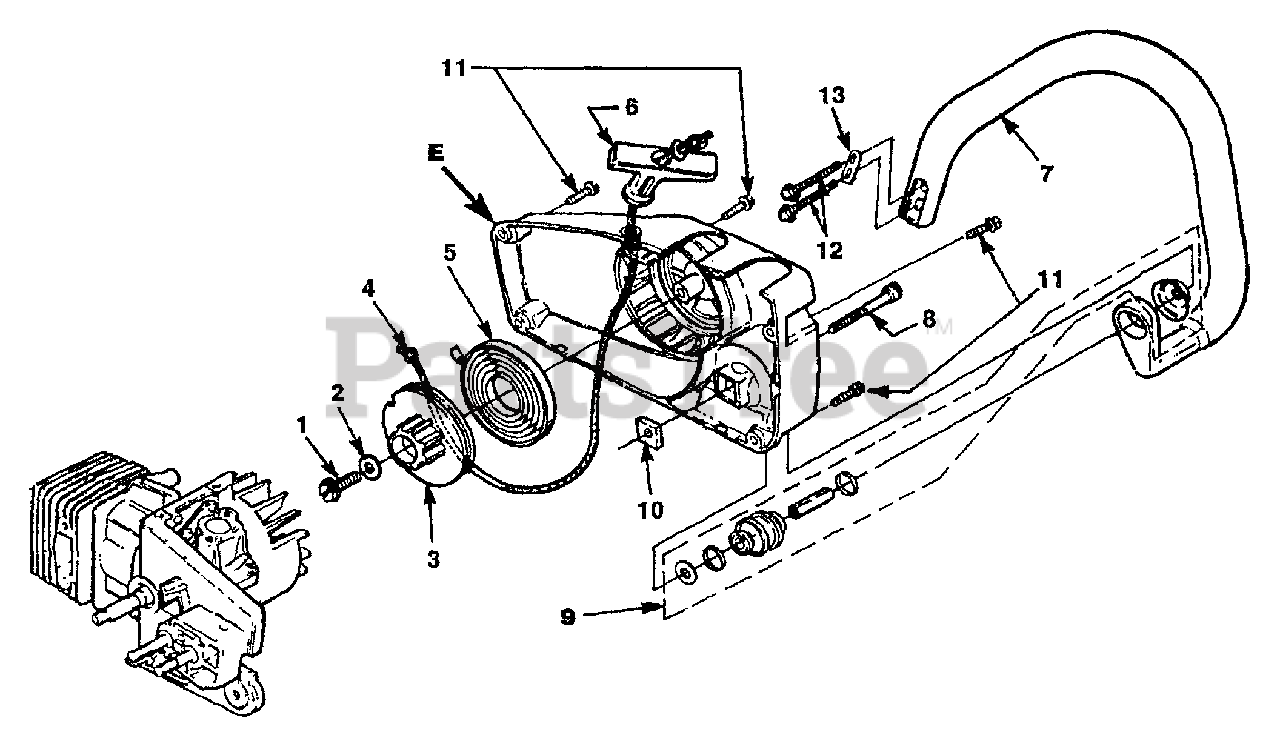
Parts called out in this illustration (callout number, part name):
1	SCREW- Thread Forming (#10 X 3/4")
2	WASHER-Retainer
3	PULLEY-Starter
4	ROPE-Starter
5	SPRING & CONTAINER
6	GRIP-Starter
7	HANDLE BAR KIT
8	SCREW-Socket Hd. (10-24 X 5/8")
9	VIBRATION ISOLATOR KIT
10	NUT-Square (10-24)
11	SCREW-Thread Form (10-24 X 3/4")
12	SCREW-Hex Washer (10-24 X 1 1/8")
13	PLATE-Handle Bar
E	STARTER, Complete
